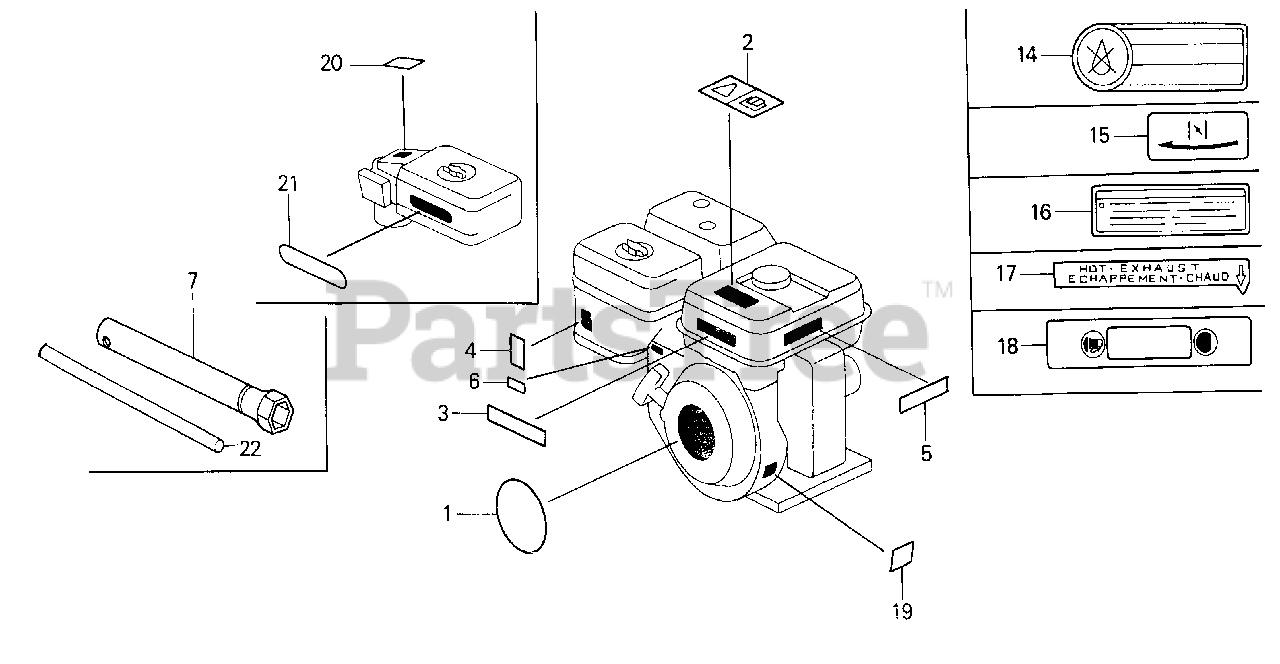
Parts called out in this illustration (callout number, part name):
1	EMBLEM (INTERNAL)
1	EMBLEM (5.5)
3	LABEL, CAUTION
4	MARK, CHOKE
5	MARK, OIL ALERT (GERMAN)
5	MARK, OIL ALERT (FRENCH)
5	MARK, OIL ALERT (E)
7	WRENCH, SPARK PLUG
